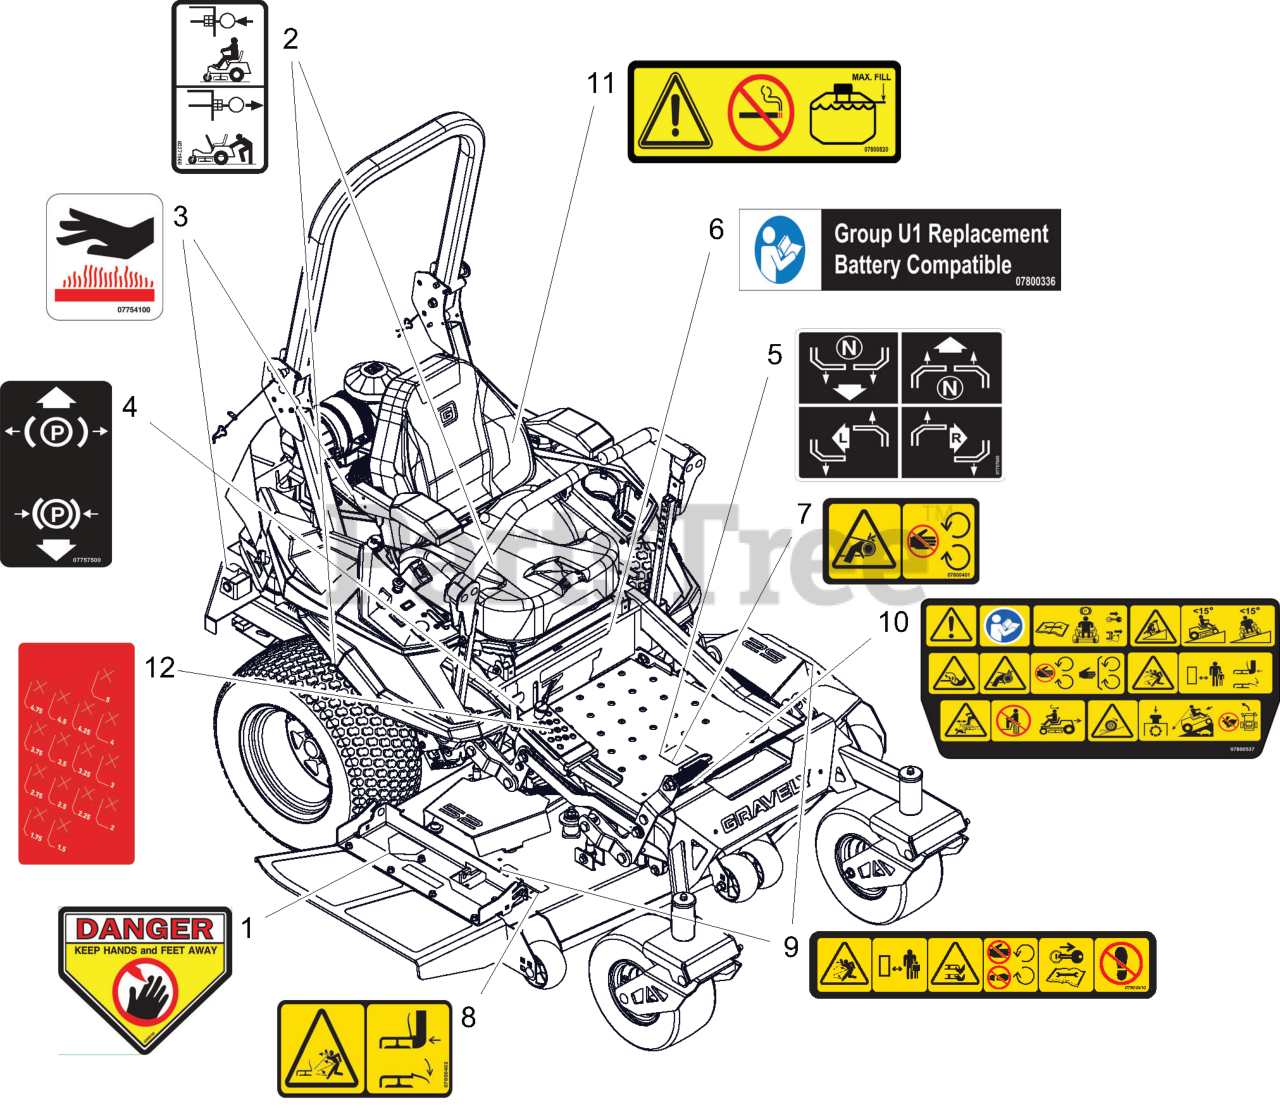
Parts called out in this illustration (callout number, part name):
1	DECAL, DANGER
2	DECAL, TRANSMISSION DISCONNECT
3	DECAL, HOT SURFACE
4	Decal, Parking Brake Lever
5	DECAL, INSTRUCTIONAL-STEERING
6	DECAL, U1 BATTERY REPLACEMENT
7	DECAL, SAFETY - GUARDING
8	Decal, Safety - Deck Guarding
9	DECAL, DECK SAFETY
10	DECAL, MAIN SAFETY
11	DECAL, FUEL WARNING
12	DECAL, HEIGHT OF CUT
